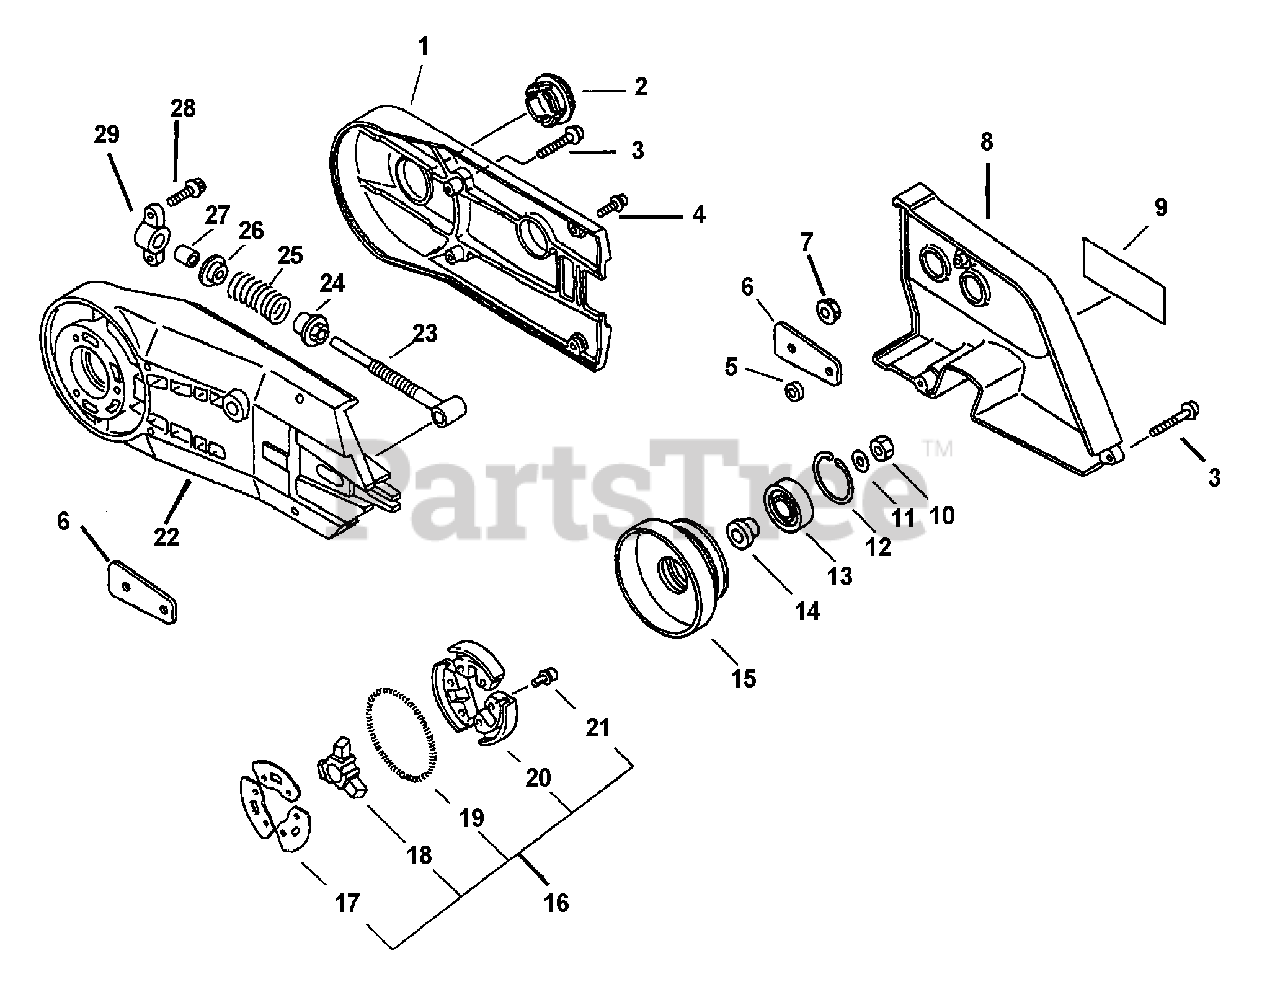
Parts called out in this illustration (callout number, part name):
1	COVER, ARM - FRONT
3	SCREW - 5X25
4	SCREW - 5X20
5	WASHER - 8
6	SPACER, ARM
7	NUT - FLANGE
8	COVER, ARM
9	LABEL - ECHO
10	NUT - 8 -- LEFT HAND
11	WASHER, CLUTCH
12	RING, RETAINING - 32
13	BEARING, BALL - 6201
15	DRUM, CLUTCH
16	CLUTCH ASSY
17	PLATE, CLUTCH
18	HUB, CLUTCH
19	SPRING, CLUTCH
20	CLUTCH SHOE SET
21	SCREW - 4X6
22	COVER, V-BELT
23	ROD, ADJUST
24	ADJUSTER
25	SPRING, ADJUST
26	SEAT, SPRING
27	SPACER, SHAFT
28	SCREW - 5X20
29	SUPPORT
